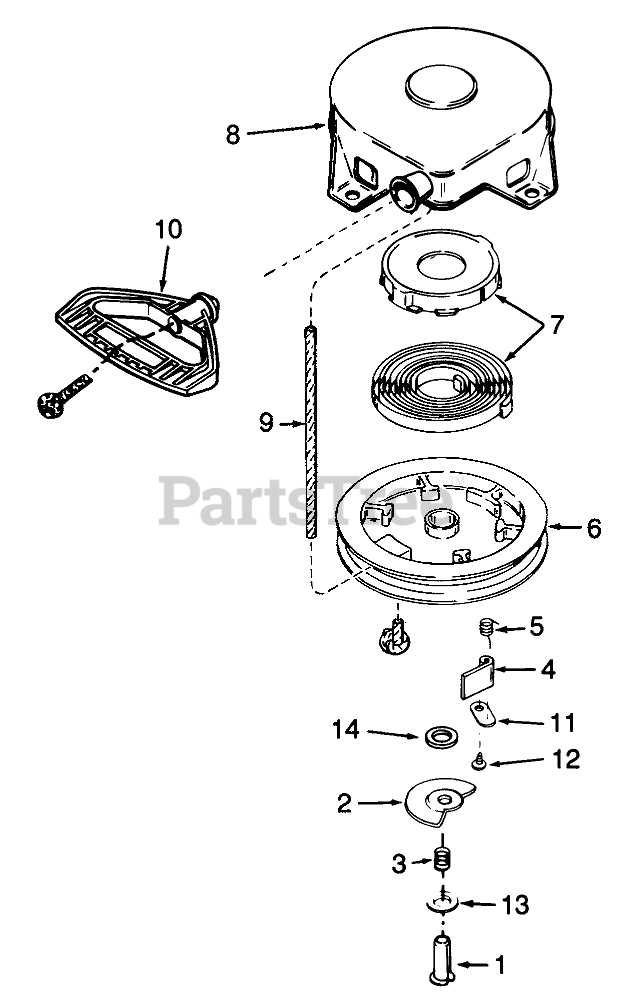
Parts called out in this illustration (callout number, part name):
1	Pin-Spring (Incl. Ref. #14)
3	Brake Spring
4	Dog-Starter
5	Spring-Dog
7	Spring & Keeper Assy
8	Housing-Starter
9	Rope-Starter
10	Handle-Starter, Mitten Grip
11	Retainer-Dog
